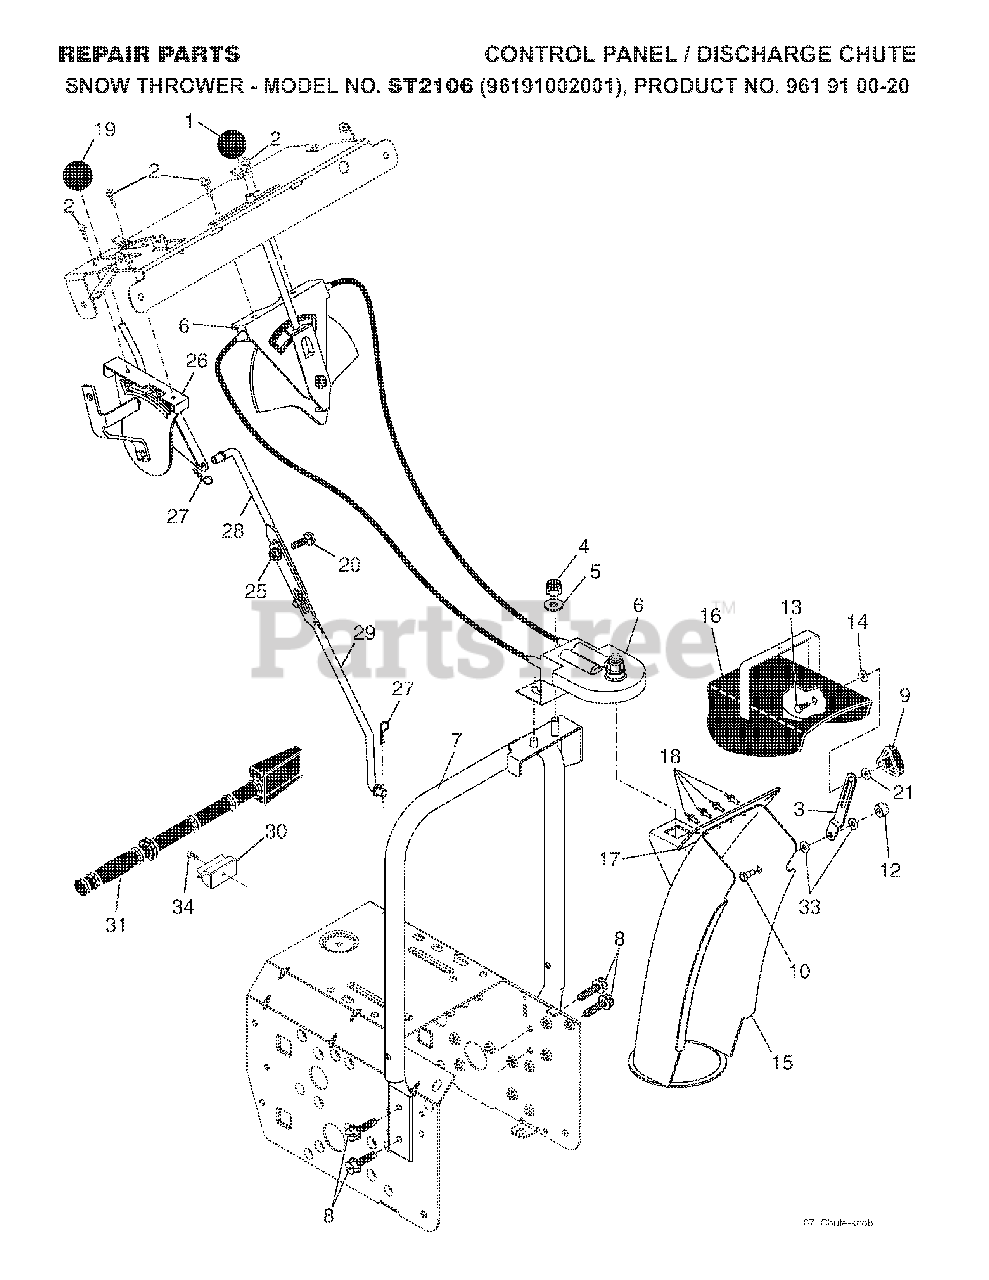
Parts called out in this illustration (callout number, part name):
1	KNOB LEVER, BLACK
2	SCREW #10-24 X 5/8
3	STRAP, CHUTE
4	NUT
6	CONTROL ASSEMBLY,CHUTE ROTATER
7	SUPPORT, PIVOT
8	SELF-TAPPING SCREW 5/16-18X3/4
9	KNOB, DEFLECTOR
10	SHOULDER BOLT
12	NUT.HEX.FLANGE.1/4
13	BOLT
14	WASHER, NYLON FRICTION
17	SEAL, DEFLECTOR
18	RIVET BLIND
19	RED KNOB SHIFTER
21	WASHER.20X8.5
25	NUT.FLANGE.5/16
26	HEAD ASSY SPEED
27	SPRING RETAINER
28	ROD, UPPER SPEED CONTROL
29	ROD, LOWER SPEED CONTROL
30	CLIP.CLEANOUT.TOOL
31	CLEAN OUT TOOL
32	SCREW.HWH.13-16-5.8.BZP
